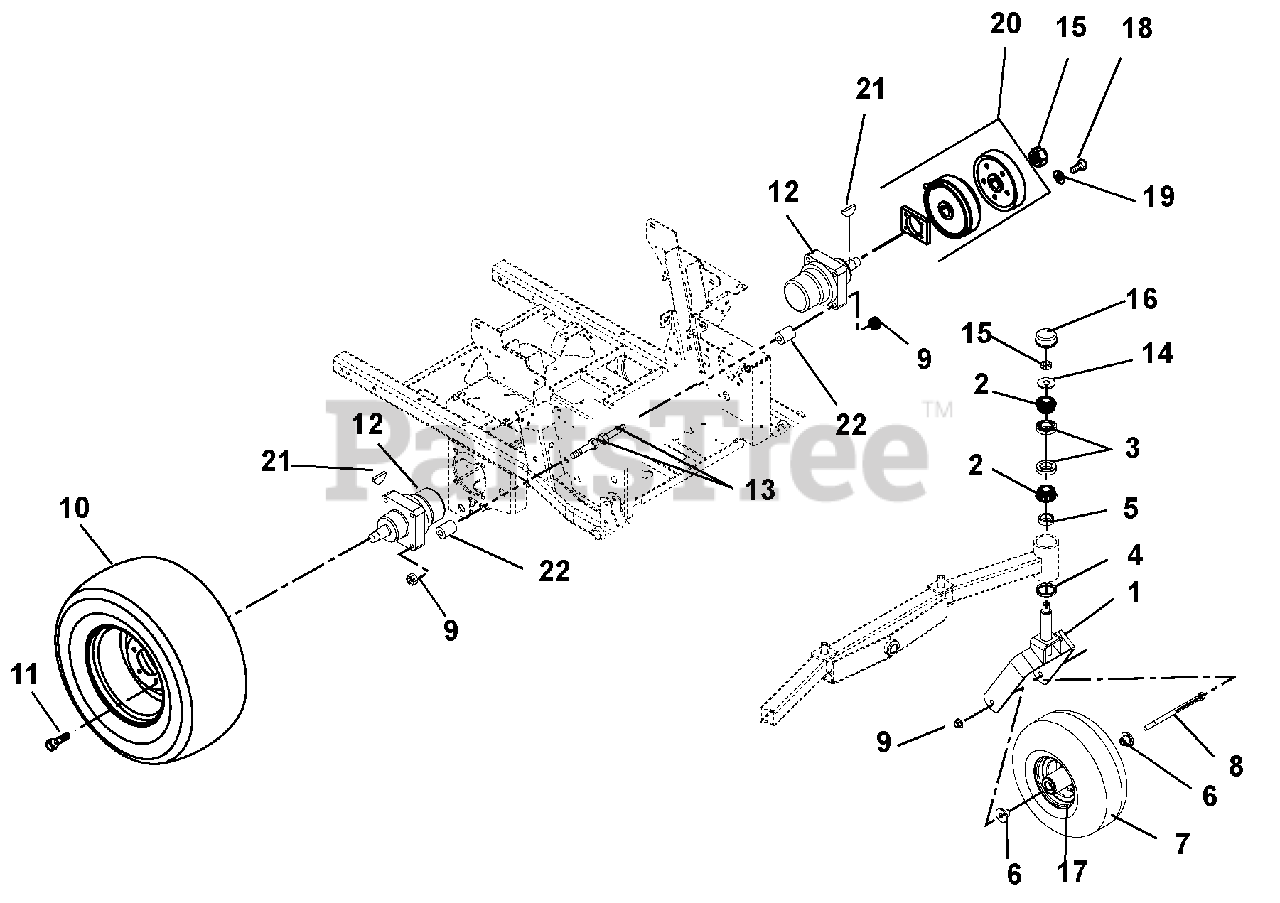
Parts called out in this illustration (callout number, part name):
1	Fork, Front
2	Bearing, Cone
3	Bearing, Cup 2.328 x .465
4	Bearing Seal 1.75 x 2.332 x .312
5	Spacer, 1.258ID x 1.750OD x .550
6	Spacer, Wheel
7	Wheel/Tire Assembly, 15 x 6-6, Smooth
7	Tire, 15 x 6-6, Smooth
8	Bolt, Hex .50-13 x 9.00 Grade 5
9	Nut, Locking Top Flange .50-13
10	Tire/Wheel Assembly, 24 x 11.50-12
10	Tire, 24 x 11.50-12
11	Bolt, Lug .50-20 x 1.38
12	Wheel Motor, Parker
13	Bolt, Wheel Motor .50-13 x 2.75 (992212)
13	Bolt, Wheel Motor .50-13 x 5.00 (992210, 213, 217, 219)
14	Washer, Flat Steel .812 x 2.00 x .148
15	Nut-Jam CTRLK .75-16 YWZC
16	Cap, Dust
17	Bearing, 25mm I.D. x 52mm OD x 15mm
18	Bolt, Hex .31-18 x 1.50 Grade 8 EP30
19	Waher, Lock .31 x .078
20	Kit, Parking Brake Service
21	Key, Woodruff .31 x 1.00
22	Bushing, .513 x .748 x 2.129 (992210, 213, 217, 219)
